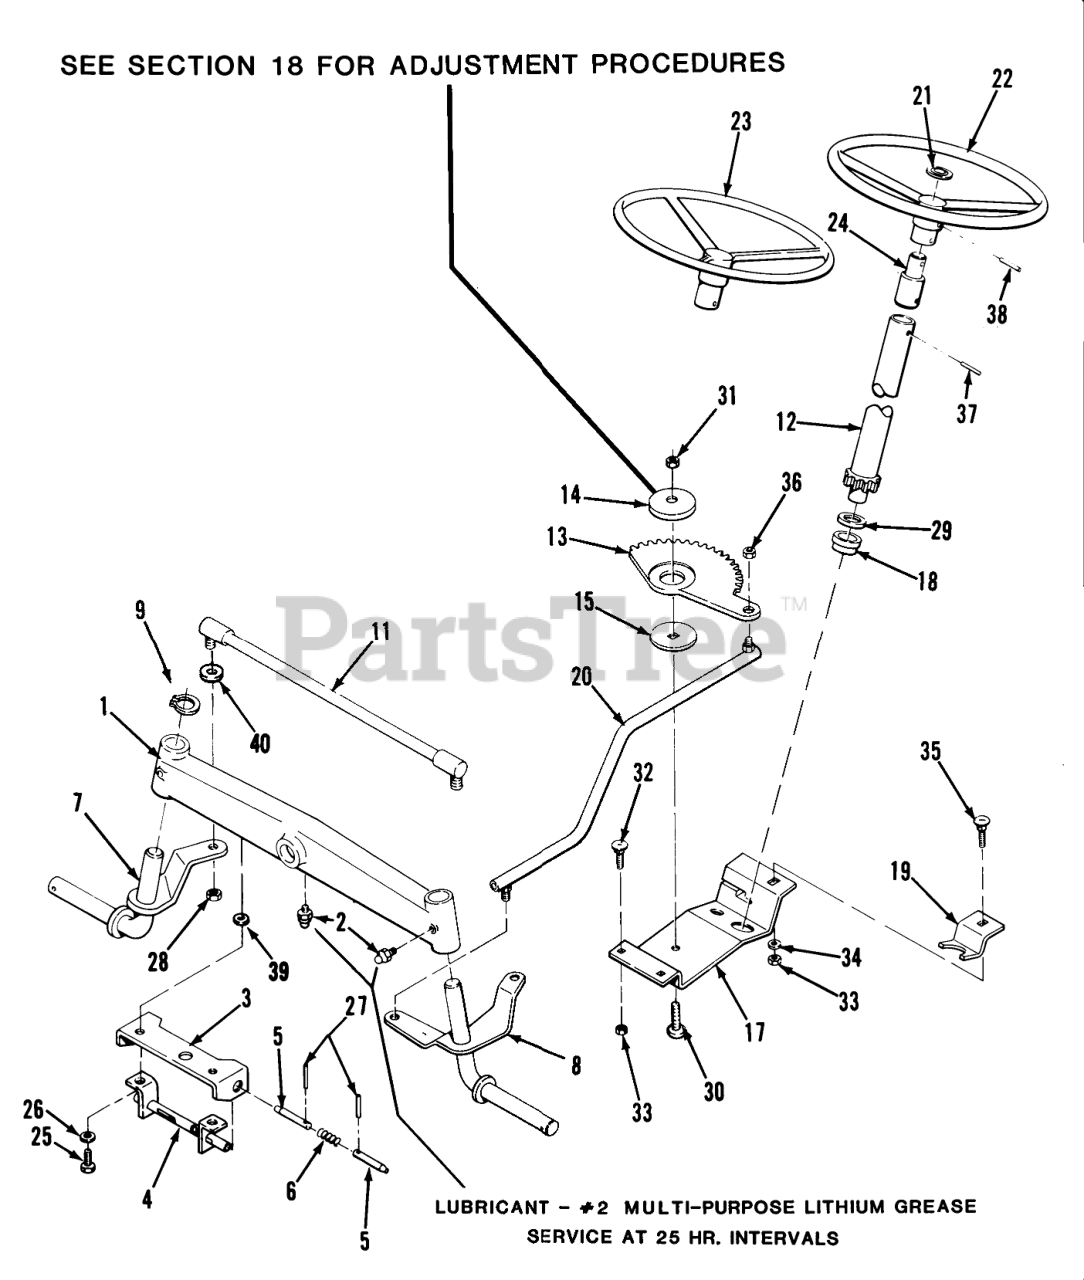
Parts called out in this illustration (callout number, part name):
1	Axle-Front
2	Zerk
3	BRACKET-SUPPORT R
4	TUBE & BRACKET ASM R
6	SPRING
7	ASSY ARM STEERING R
8	ASSY ARM STEERING R
9	Snap Ring
11	ASS'Y-TIE ROD R
12	ASSY PINION & SHA B
13	GEAR SECTOR
14	BUSHING
15	WASHER-BEARING
17	BRKT-STEERING GEAR
18	BEARING-WHEEL
19	RETAINER R (NS)
20	ASSY BALL JOINT L R
21	INSERT-STEERING WHL
22	STEERING WH 13" SOFT
23	WHEEL STEERING
24	SHAFT COUPLER
25	HHCS
26	Lockwasher
27	SPIROL PIN
28	Nut-Lock
29	WASHER
30	Bolt-Carriage
32	Bolt
33	Nut
34	WASHER 5/16 SAE
35	Bolt-Carriage
36	NUT-6
37	SPIROL PIN 5/16X13/8
38	Pin-Roll
39	WASHER
40	WASHER-SPECIAL
